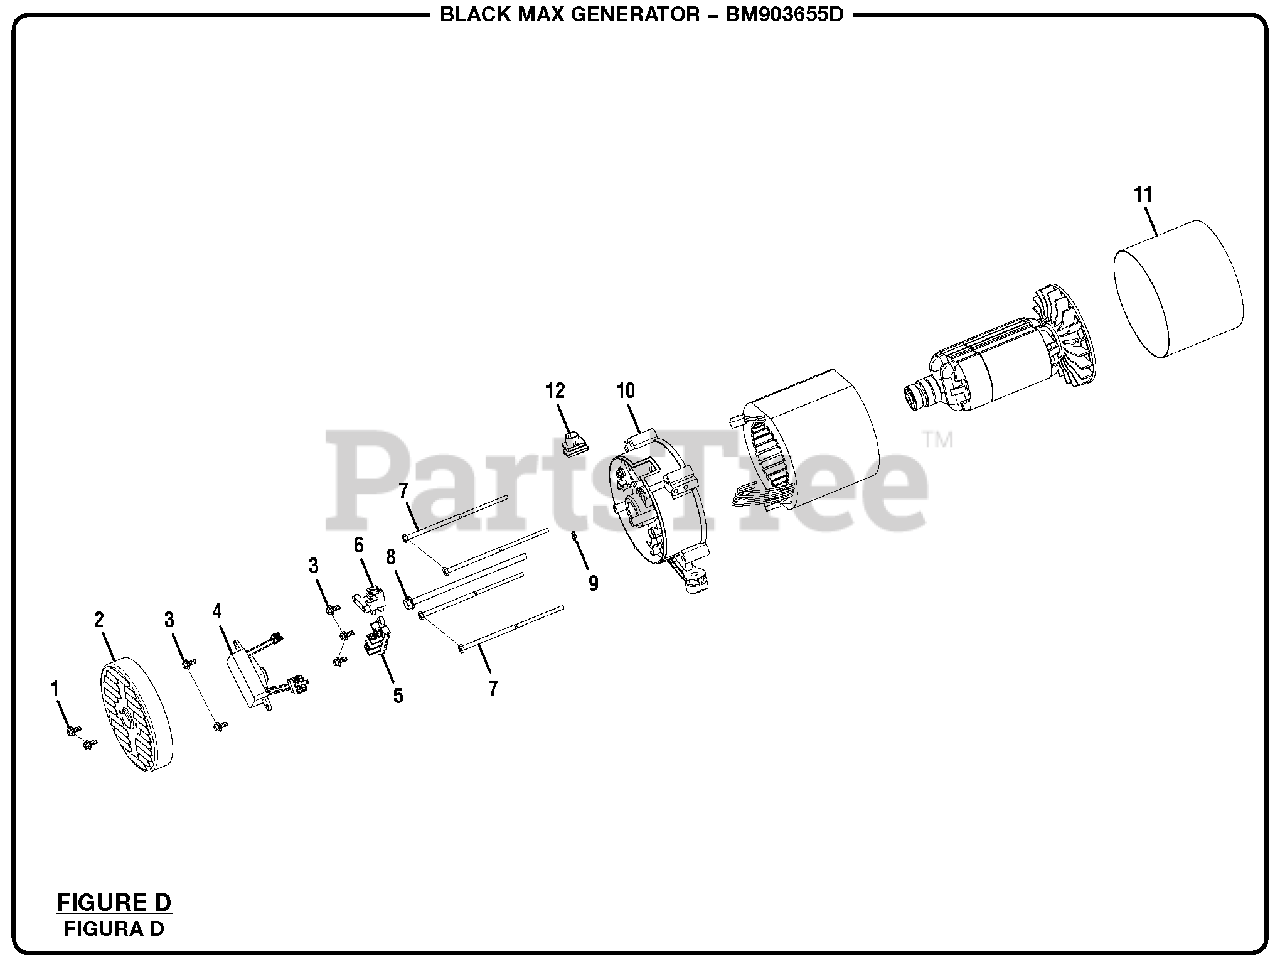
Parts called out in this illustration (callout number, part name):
1	Bolt (M5 x 12 mm, Hex Hd)
2	Brush Cover
3	Bolt (M5 x 16 mm, Hex Hd)
4	Automatic Voltage Regulator
5	Terminal Block
6	Brush Assembly
7	Stator Bolt
8	Rotor Bolt
9	Lock Washer (5/16 in)
10	Bearing Support
12	Rubber Boot
